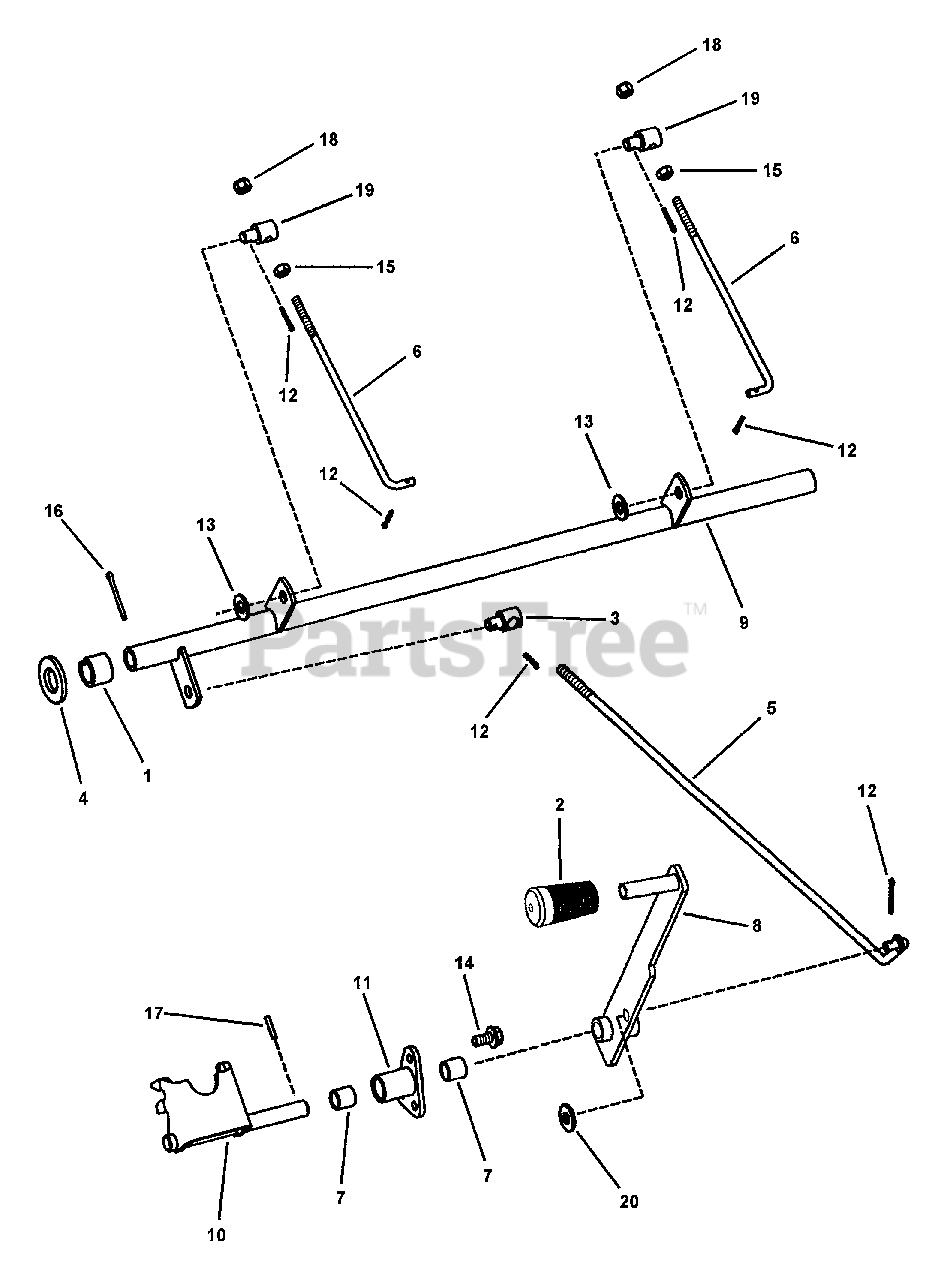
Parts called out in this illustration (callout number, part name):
1	RING, Rear Lift Arm (Blue)
2	GRIP, Round Bar (23 HP Gas Engine)
3	SWIVEL, Adjustable
4	WASHER, 3/4 I.D. x 1-1/2 O.D. x 9/64" Flat
5	ARM, Brake Lift
6	ROD, Hydrostatic Brake
7	SLEEVE Bearing, 1/2 I.D. x 5/8
8	WELDMENT, Parking Brake Arm
9	WELDMENT, Brake Shaft
10	WELDMENT, Joystick Lockout Bracket
11	WELDMENT, Support Plate
12	COTTER PIN, 3/32 x 3/4"
13	WASHER, 3/8" Flat
14	SCREW, 5/16-18 x 5/8" Hex Washer Face Self-Tap
15	NUT, 1/4-28 Hex, Grade 5 or B
16	COTTER PIN, 1/8 x 1-1/4
17	PIN, Roll 1/8 x 3/4"
18	NUT, 1/4-28 Hex Nyloc
19	SWIVEL, 1/4" Smooth
20	WASHER, 3/8" I.D. x 7/8" O.D. Flat
